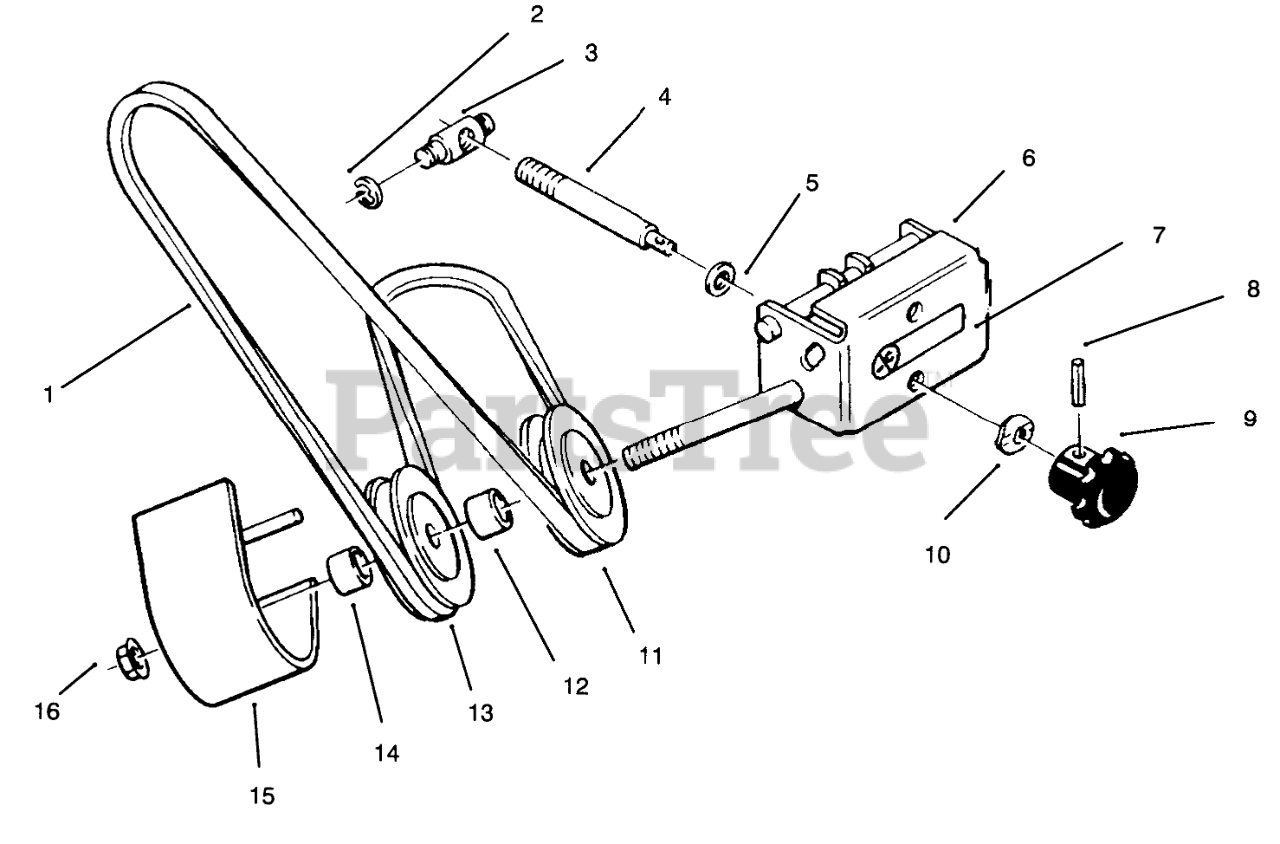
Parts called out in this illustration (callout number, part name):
1	V-BELT
2	RING-RETAINING
3	TRUNNION-DOUBLE
4	ROD ADJ
5	WASHER-FLAT
6	Front Support
7	DECAL-ATTACHMENT
8	PIN-ROLL
9	KNOB-ADJUSTMENT
10	WASHER-SPRING
11	Pulley-V
12	SPACER
13	PULLEY-FLAT IDLER
14	SPACER-OUTER
15	Belt Cover
16	Nut
